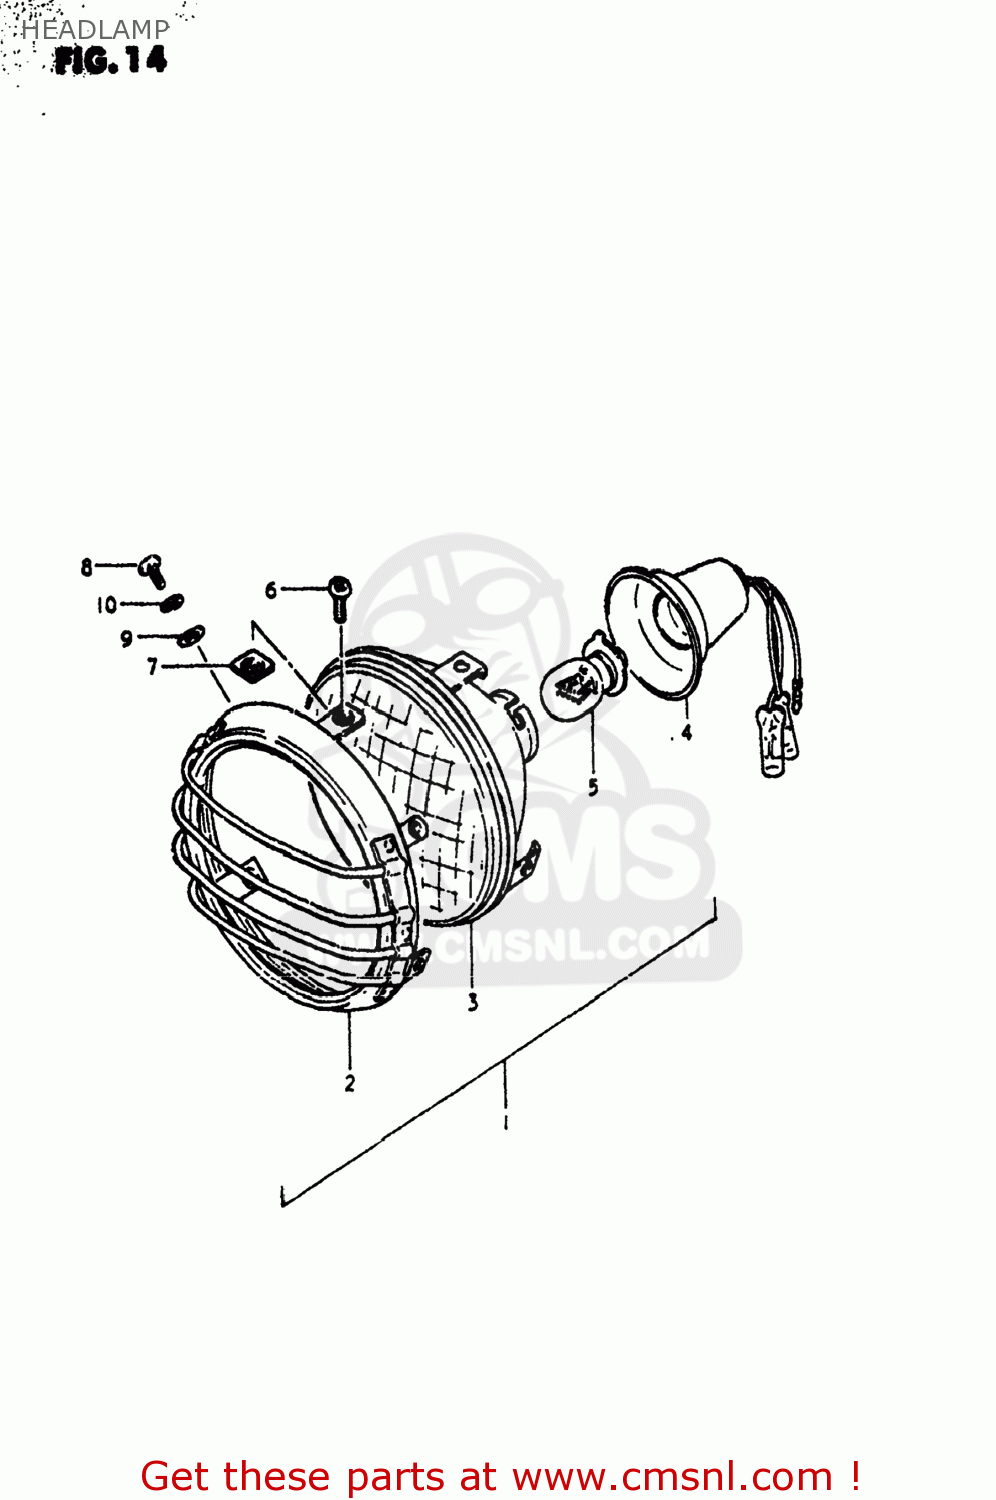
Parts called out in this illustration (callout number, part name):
1	HEADLAMP ASSEMBLY
2	RIM,HEADLAMP
3	LAMP UNIT
4	SOCKET,HEADLAMP
5	BULB(6V15/15W/STANLEY,A3598HA)
6	SCREW
7	NUT
8	SCREW
9	WASHER
10	LOCK WASHER
